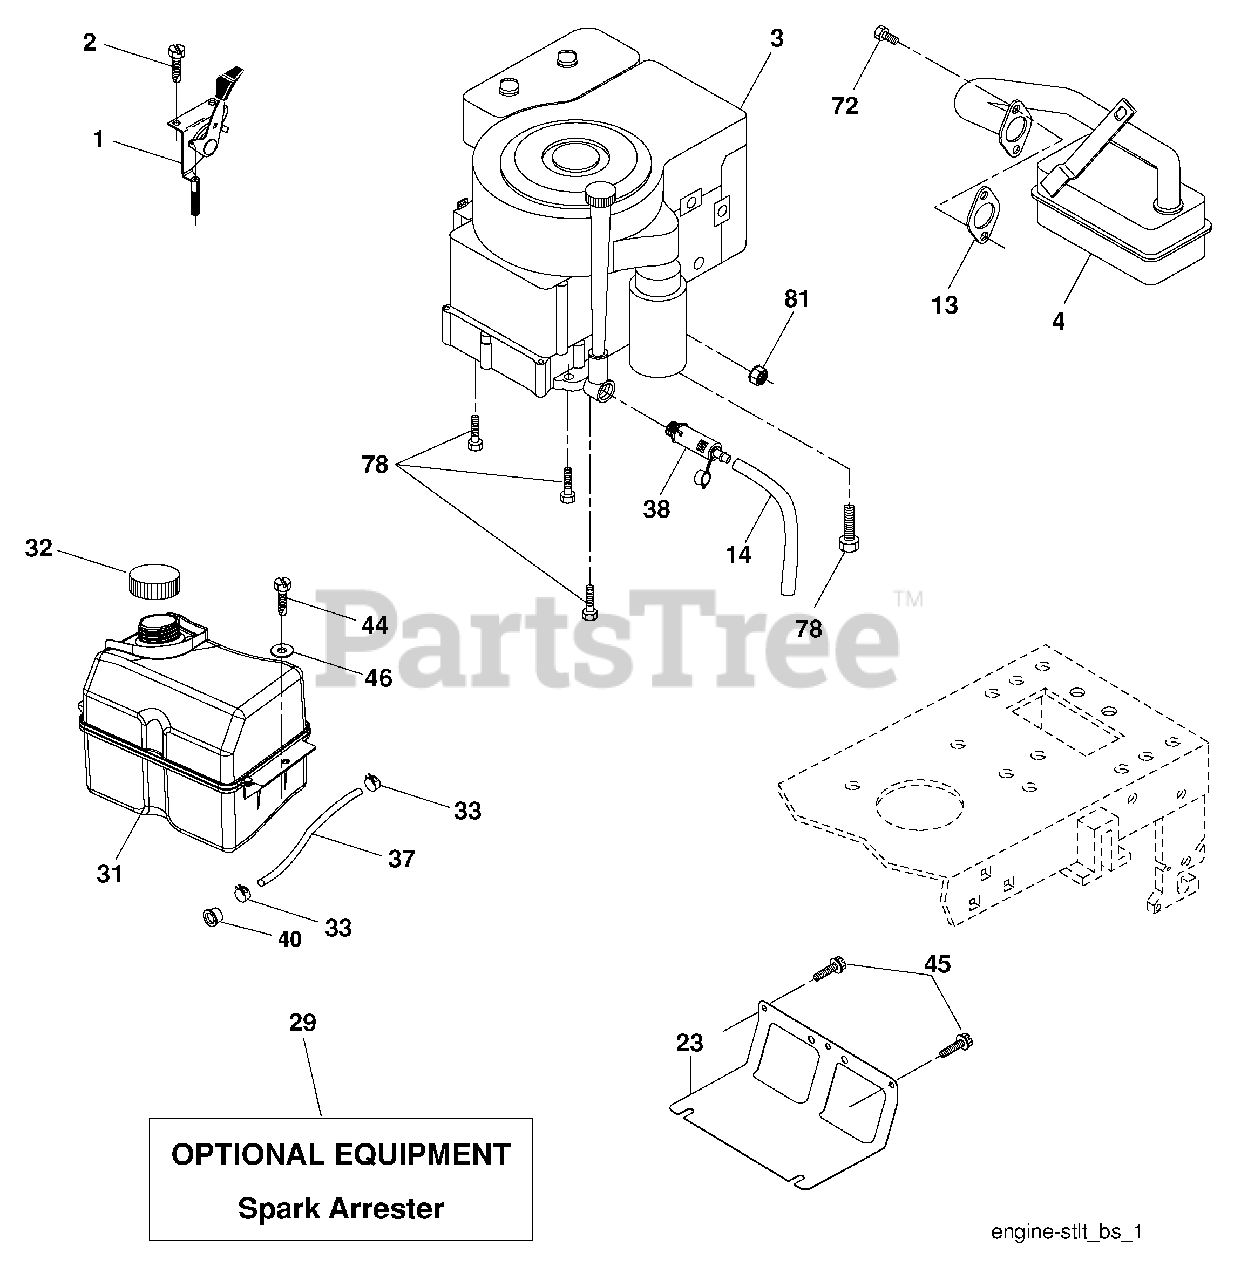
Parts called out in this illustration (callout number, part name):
1	Control Th/ch Flag
2	Screw Hex Thd Cut 1/4-20 x 1/2
4	Muffler Exhaust B&S
13	Gasket Eng 1 313 Id Tin Plated
14	Tube Drain Oil Easy
23	Shield BRN/DBR Guard
29	Kit Spark Arrester (Flat Scrn)
31	Tank Fuel Front
32	Cap Asm Fuel
33	Clamp Hose
37	Line Fuel 20"
38	Plug Drain Oil
40	Bushing Snap Nyl Blk Fuel Line
44	Screw Thdrol 1/4-20 x 3/4
45	Screw Hex Wsh Thdrol 3/8-16
46	Washer 9/32 x 7/8 x 16 Ga.
72	Screw Socket Head 5/16-18 x 3/4
78	Screw 3/8-16 x 1-1/4
81	Nut Keps Hex 1/4-20 unc
